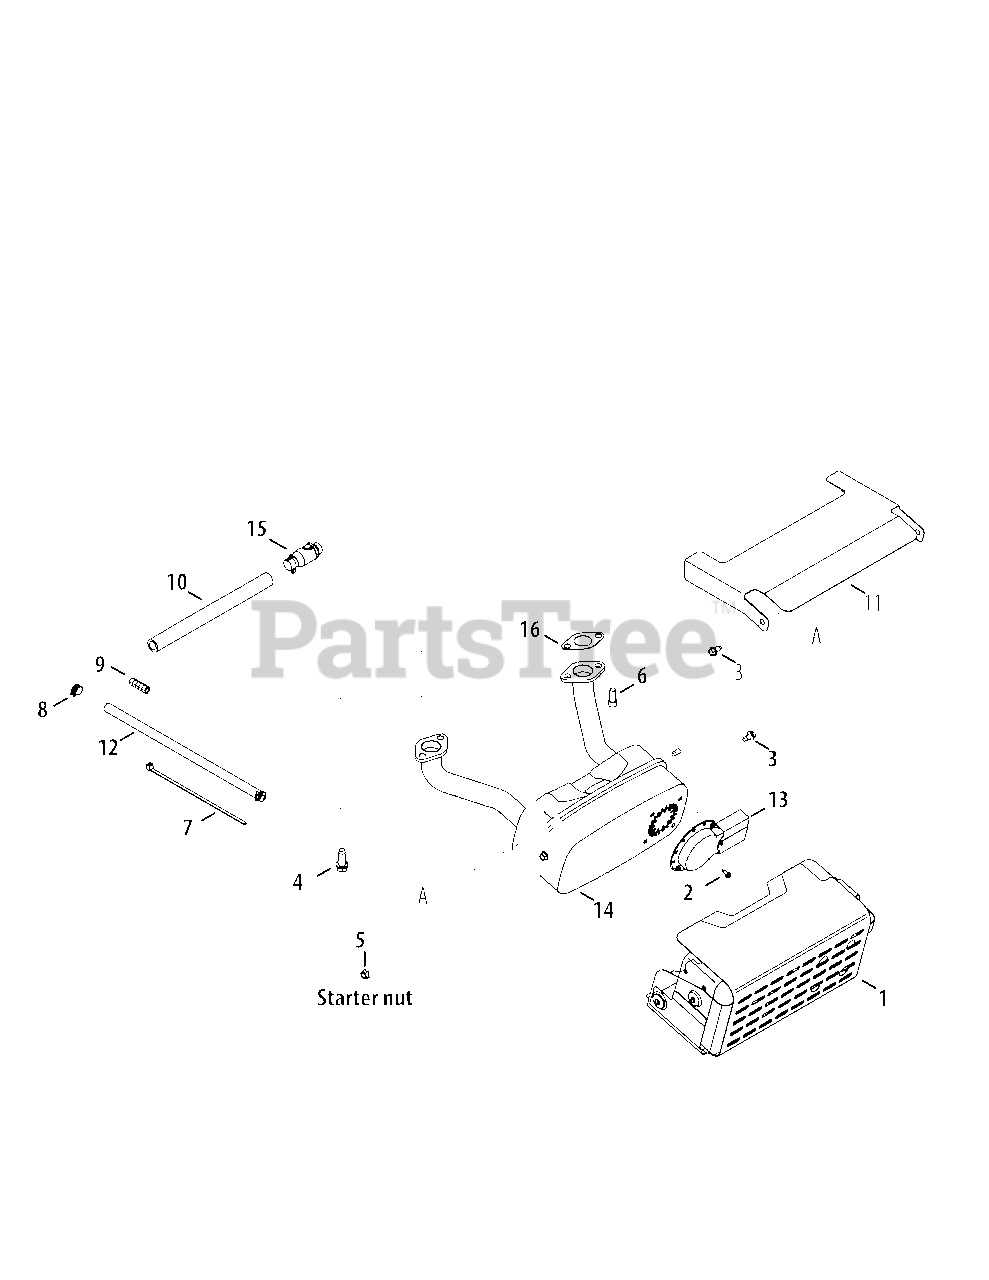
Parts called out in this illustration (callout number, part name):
1	Shield Ass’y, Muffler
2	Screw, Ab, #8-18, 0.500,
3	Screw, Self-tapping, 1/4-20, 0.500,
4	Screw, Self-tapping, 3/8-16, 1.0
5	Nut, Sems, 1/4-20
6	Screw, Sokt Head, 5/16-18, .750
7	Cable, Tie, 3/16 x .05 x 7.4
8	Clamp, Hose, .490 Dia.
10	Hose, Extension, Oil Drain
11	Heat Shield
12	Hose, Fuel, Low Permeation, 1/4
13	Deflector, Muffler, Long
14	Muffler, Kohler
16	Gasket, Exhaust
